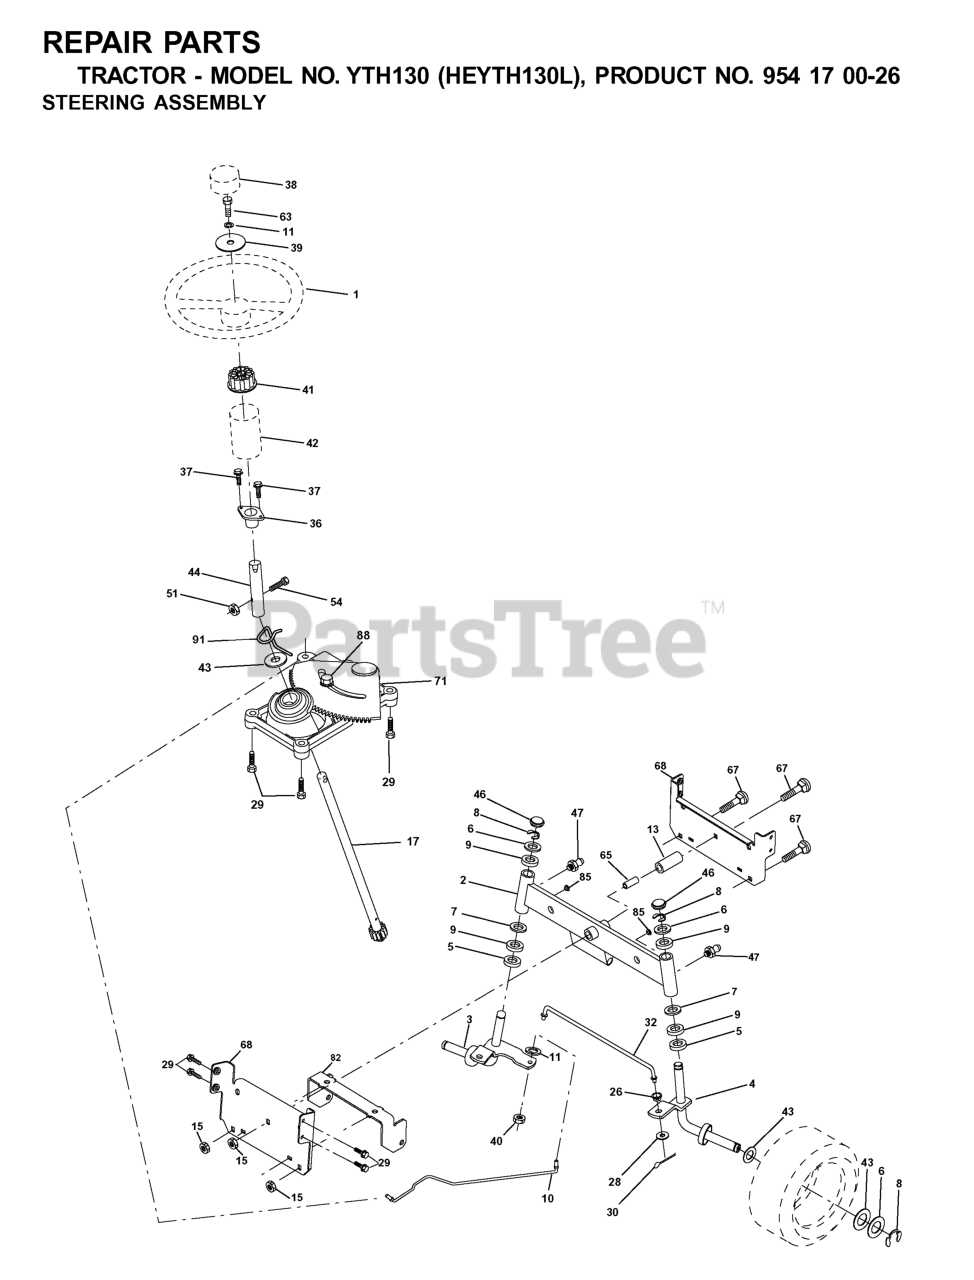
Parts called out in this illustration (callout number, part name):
1	STEERING WHEEL
2	AXLE ASSY
3	SPINDLE.ASM.LH.15"TIRES
4	SPINDLE.ASM.RH.15"TIRES
5	THRUST WASHER
9	BRNG T
10	DRAGLINK.15".TIRES.2001
11	WASHER, LOCK 3/8
13	TUBE, PIVOT AXLE
15	NUT
17	SHAFT ASM
26	BUSHING.DRAGLINK (2 2)
28	WASHER
29	SCREW 3/8-16X3/4
30	COTTER PIN
32	TIE ROD
36	BUSHING, STEERING
37	SCREW.TT.#10-32X.5.3/8.FLANGE
38	CAP.WHEEL.STEERING.GREY
39	Washer 13/32 x 1-1/20 x 11 Gauge
41	STEERING WHEEL ADAPTOR
42	BOOT STEERING
44	EXT SHAFT STEERING
46	CAP.SPINDLE.BLACK
47	ZERK M
51	NUT.71038.31-18.HEX.NYLOCK
54	BOLT.5/16-18X1-1/4 FULL.THREAD
65	SPACER BRACE AXLE
67	BOLT
68	BRACE.AXLE.15"TIRES
71	STEERING ASM
82	BRACKET
85	FASTENER.XMAS.TREE
88	BOLT, SHOULDER 7/16-20
91	CLIP.STEERING
